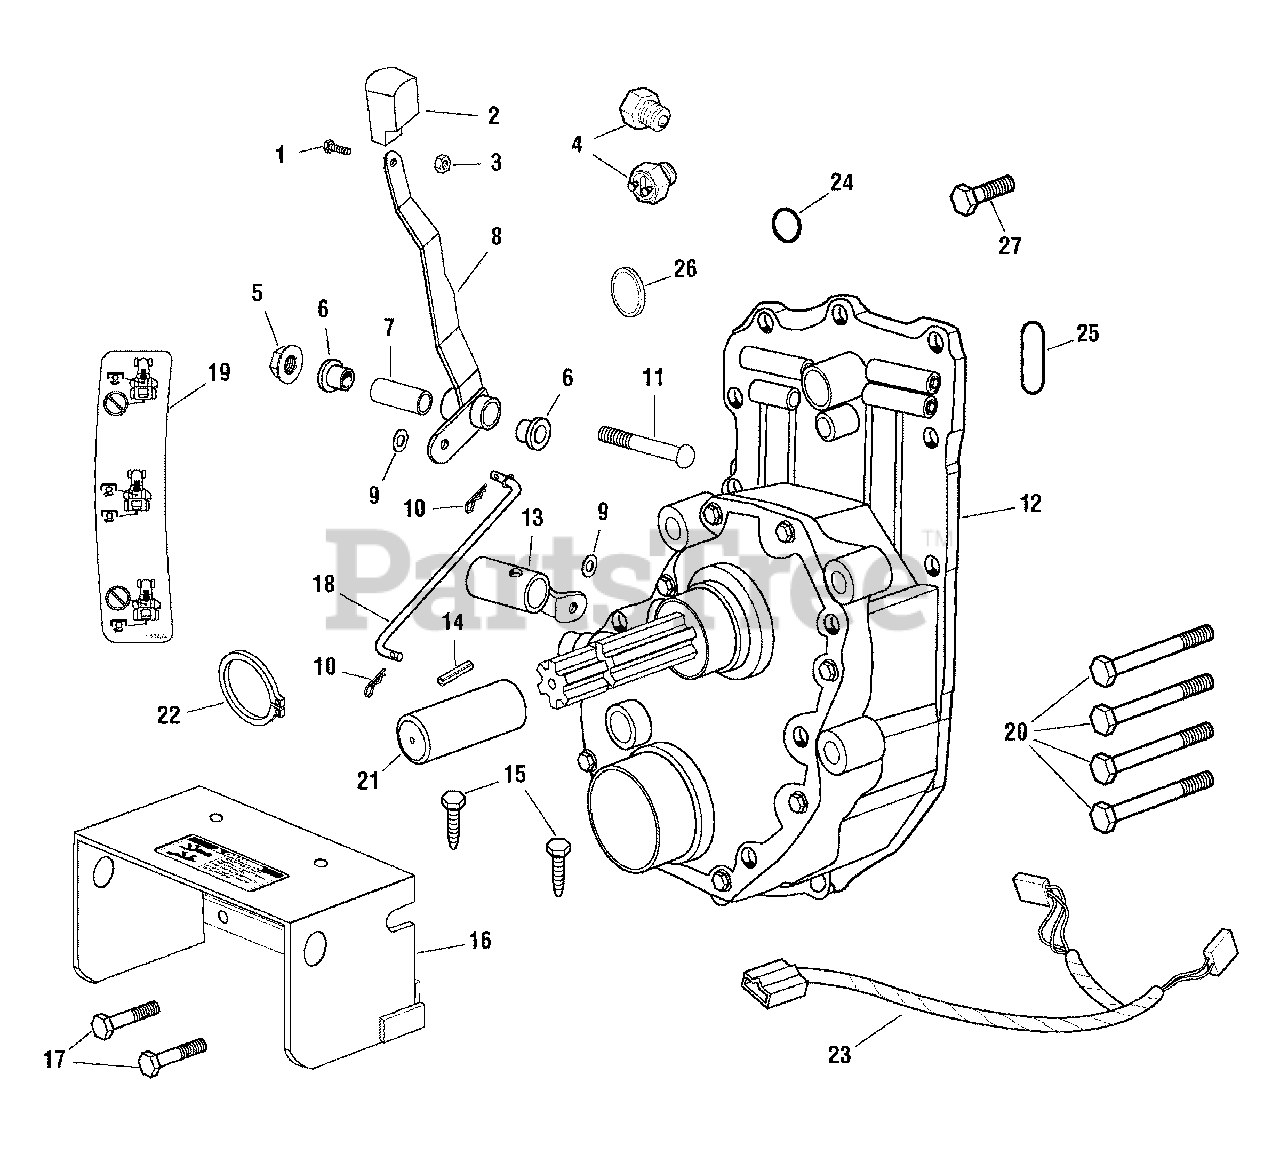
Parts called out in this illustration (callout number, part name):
1	CAPSCREW, Hex Head, 1/4 - 20 x 7/8
2	HANDLE, 540 PTO
3	NUT, Nylock, 1/4 - 20
4	SWITCH, Ball
5	NUT, Hex Washer, 3/8 -16
8	HANDLE ASSEMBLY
10	PIN, Quick
11	BOLT, Carriage, 3/8 - 16 x 2-1/2
12	PTO, 540 RPM, Tuff Torq
13	ARM & HUB ASSEMBLY
15	CAPSCREW, Hex Washer Head, 5/16 - 18 x 3/4
16	SHIELD & DECAL ASSEMBLY
17	CAPSCREW, Hex Head, M12 - 1-3/4 x 25mm
19	DECAL, 540 PTO Lever Control
20	CAPSCREW, 8mm x 90mm
21	COVER, 540 PTO
23	WIRE HARNESS
26	SOLENOID GASKET
27	CAPSCREW, 8mm x 30mm
